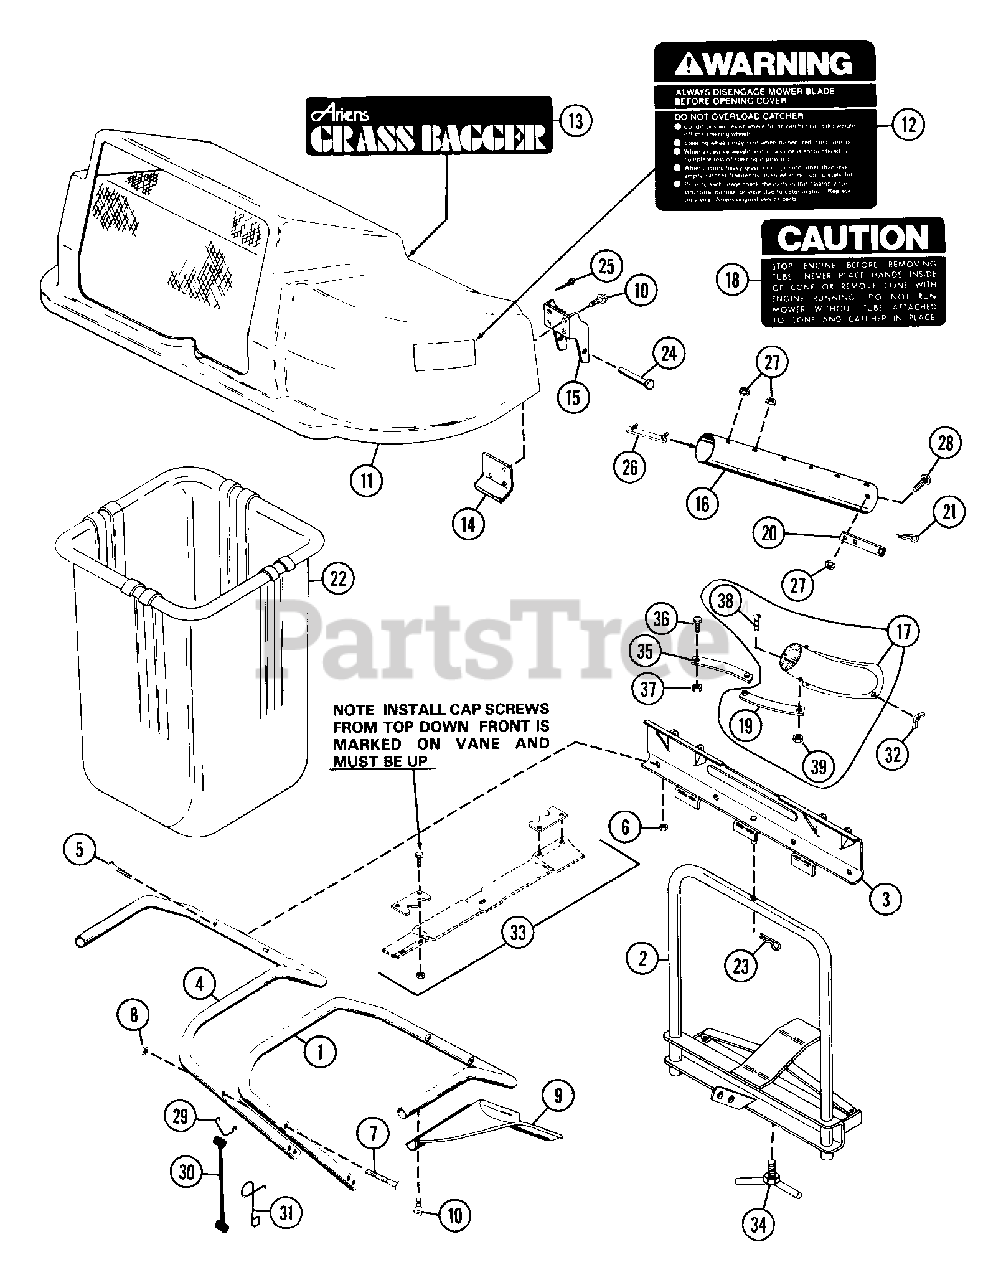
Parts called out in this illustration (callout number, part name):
1	BRACKET
2	ATTACHMENT FRAME
4	TUBE L.H. SUPPORT
5	SCR-MCH .31-18X1.50 CROVCNTRS
6	NUT-LK-NYL.312-18 PL
7	BLT-HEX .25-20X2.25 GR2
8	NUT-LK-CTR .250-20 PL
9	SUPPORT TUBE
10	BLT-SCRHFWH .25-20X.62 PL
11	GRASS CATCHER COVER ASSEMBLY
12	WARNING DECAL
13	ARIENS GRASS BAGGER DECAL
14	RETAINER
16	TUBE BLANK
17	GRASS BAGGER BOOT ASSEMBLY
18	CAUTION DECAL
19	STRAP
20	STRAP
21	PIN-HAIR INT .09X.188 PL
23	PIN-HAIR INT .08X.38X1.42 YWZC
24	CLEVIS PIN
25	PIN-COTR .06X.50
27	NUT-LK-FLG .250-20 PL
28	BLT-RDHDSQNK .25-20X.50 SHT PL
30	BATTERY STRAP
31	HOOK
32	NUT-WING W/INSERT .312 - 18
33	SERVICE VANE PACKAGE
34	T-HANDLE BOLT
35	PAN STRAP
36	BLT-HEX .31-24X.75 GR8
37	NUT-LK TOP .312-24 PL GR C
38	SCR-MCH 10-24X.38 SLTOR PAN PL
39	NUT-LK TOP 10-24 PL
